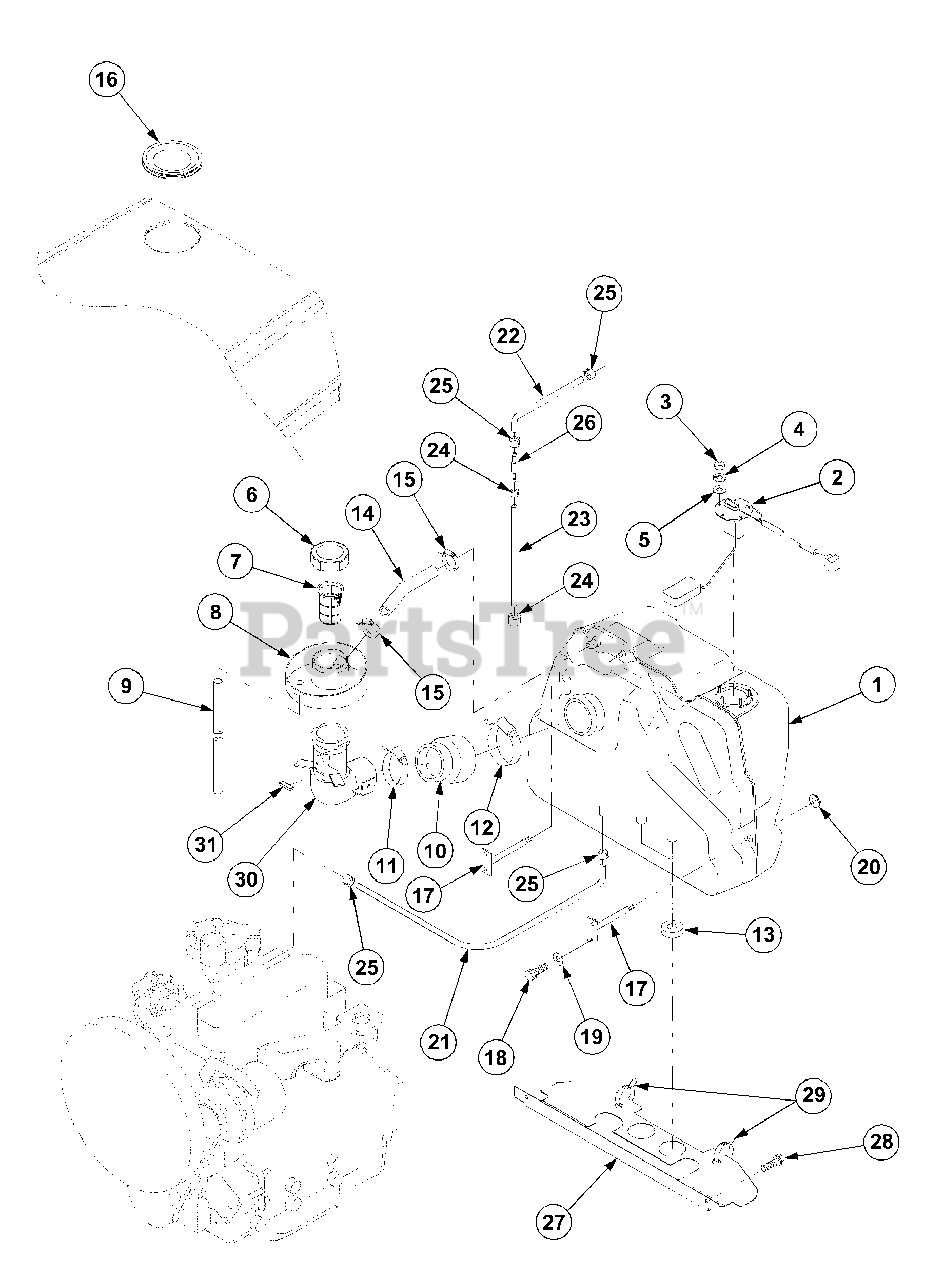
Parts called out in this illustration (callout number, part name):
4	Washer,Spring
13	Rubber,Cushion
18	Bolt,w/Washer
28	Bolt,w/Washer
